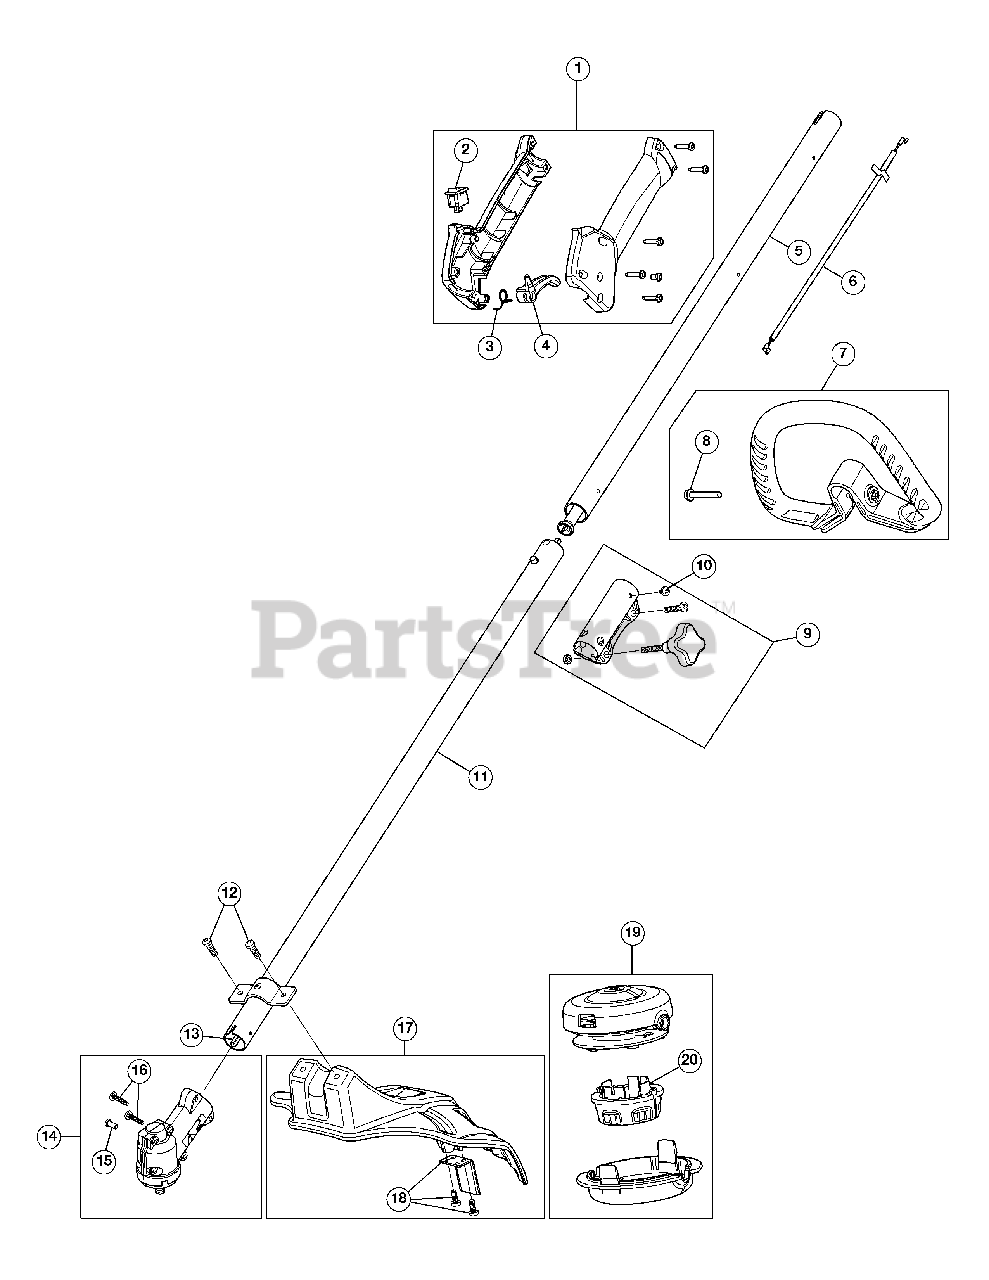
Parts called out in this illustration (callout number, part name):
1	Throttle Housing Assembly (Incl. 2 - 4)
2	Switch Assembly
3	Throttle Trigger Spring
4	Throttle Trigger
5	Upper Drive Shaft Assembly
6	Throttle Cable
7	D-Handle Assembly (Incl. 8)
9	Split Boom Coupler (Incl. 9)
10	Coupler Anti-Rotation Screw
11	Lower Drive Shaft Housing
12	Shield Mounting Screws
13	Lower Flexible Drive Shaft
14	Gearbox Assembly (Incl. 15 and 16)
15	Anti-Rotation Screw
16	Gearbox Mounting Hardware
17	Shield Assembly (Incl. 18)
18	Blade Assembly
19	Cutting Head Assembly (Incl. 20)
